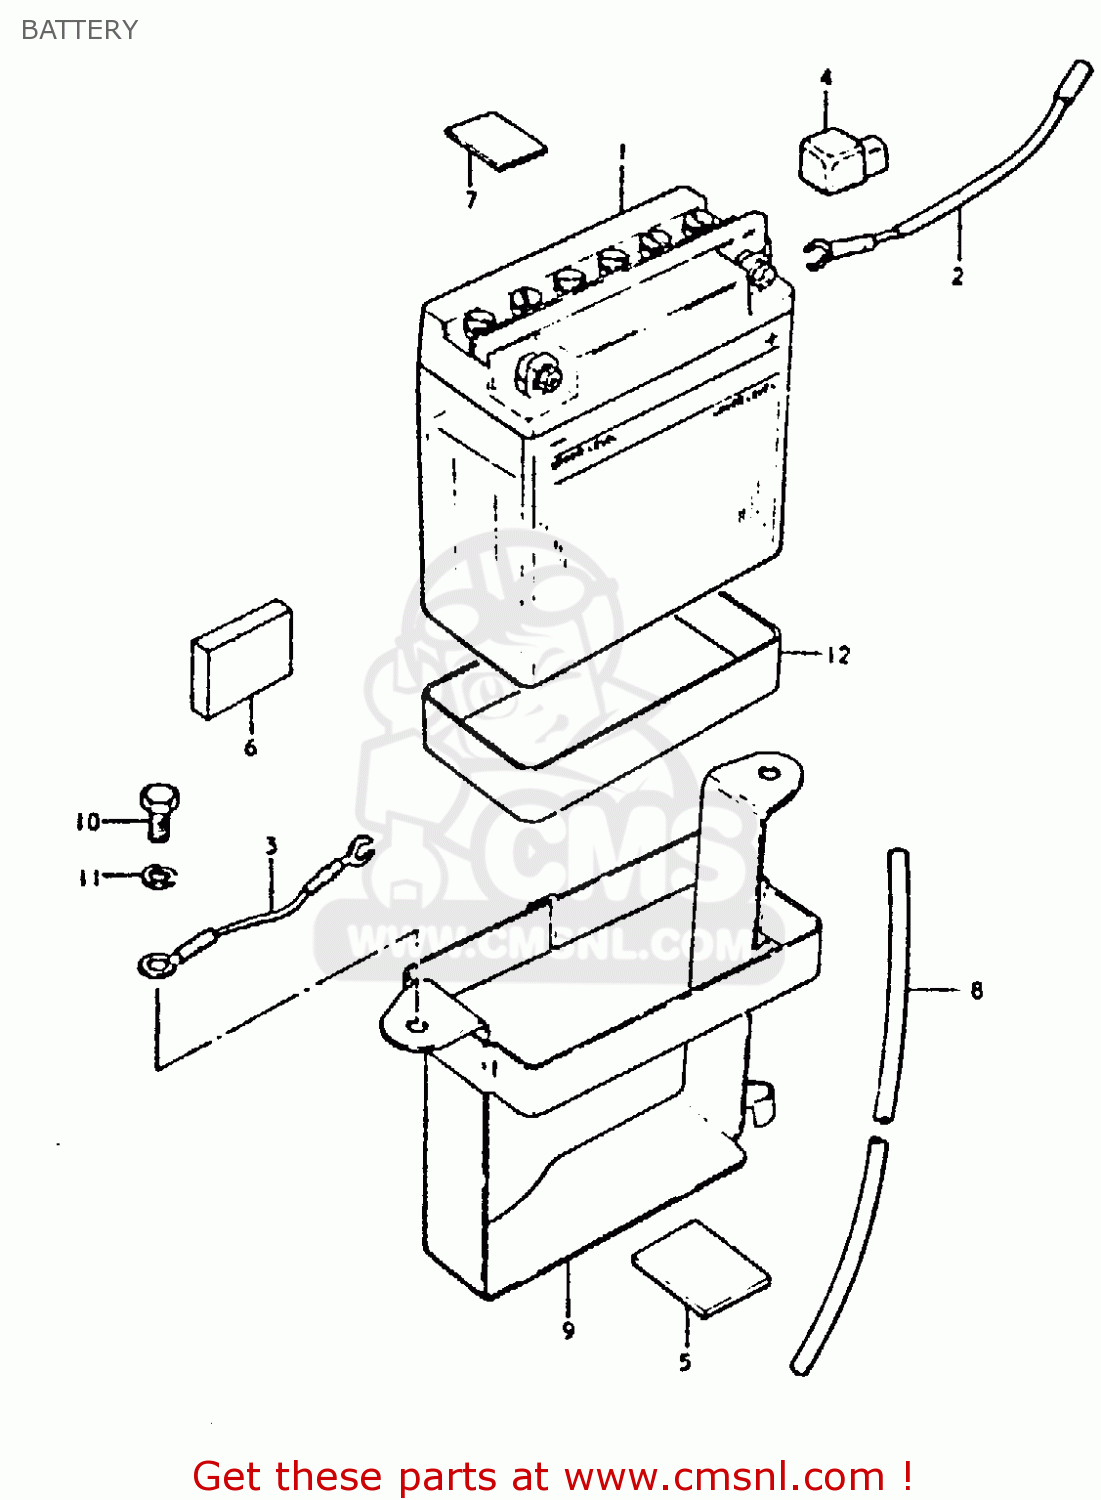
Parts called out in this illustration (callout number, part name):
1	BATTERY ASSEMBLY (12V)
2	LEAD WIRE, BATTERY (+)
3	LEAD WIRE, (-)
4	CAP,BATTERY PLUS TERMINAL
5	PROTECTOR(170X95X3.0)
6	PROTECTOR(170X95X3.0)
7	PROTECTOR, NO. 3 (40*30*2)
8	HOSE,BATTERY EXHAUST
9	HOLDER, BATTERY
10	BOLT
11	LOCK WASHER
12	BAND
